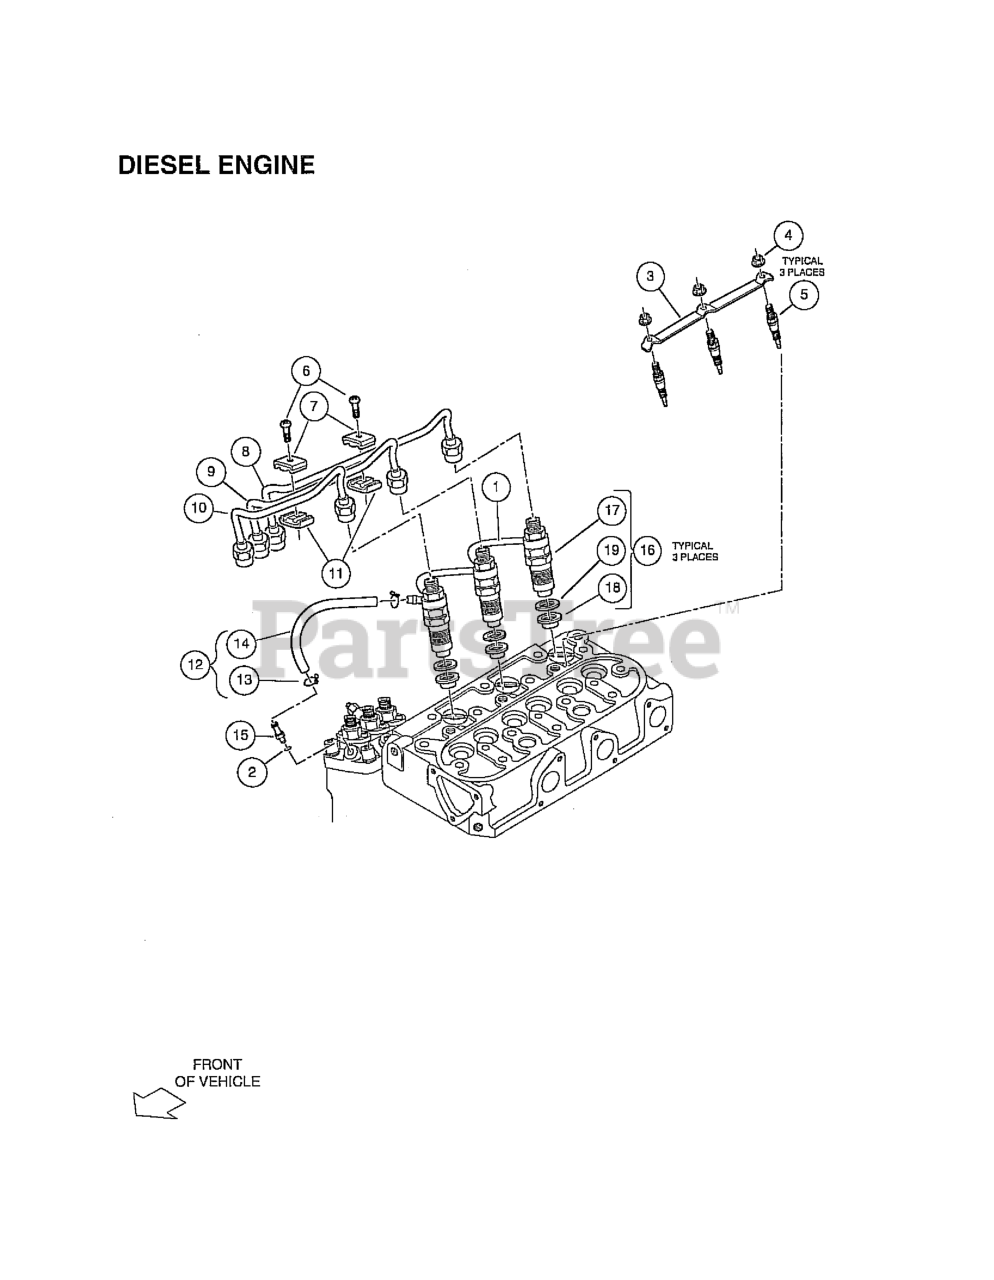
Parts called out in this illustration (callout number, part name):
2	GASKET, 6X10
3	CORD, GLOW PLUG
4	NUT, FLANGE, M4
6	SCREW-WASHER
7	CLAMP, PIPE, TOP
8	PIPE, INJECTION, LEFT
9	PIPE, INJECTION, RIGHT
10	PIPE, INJECTION, MIDDLE
11	CLAMP, PIPE, BOTTOM
12	ASSY PIPE, OVERFLOW
13	CLIP, PIPE, RETURN
15	SCREW, AIR BREEDER
16	KIT, HOLDER, NOZZLE
17	ASSY HOLDER, NOZZLE
18	SEAL, HEAT
19	GASKET, NOZZLE
